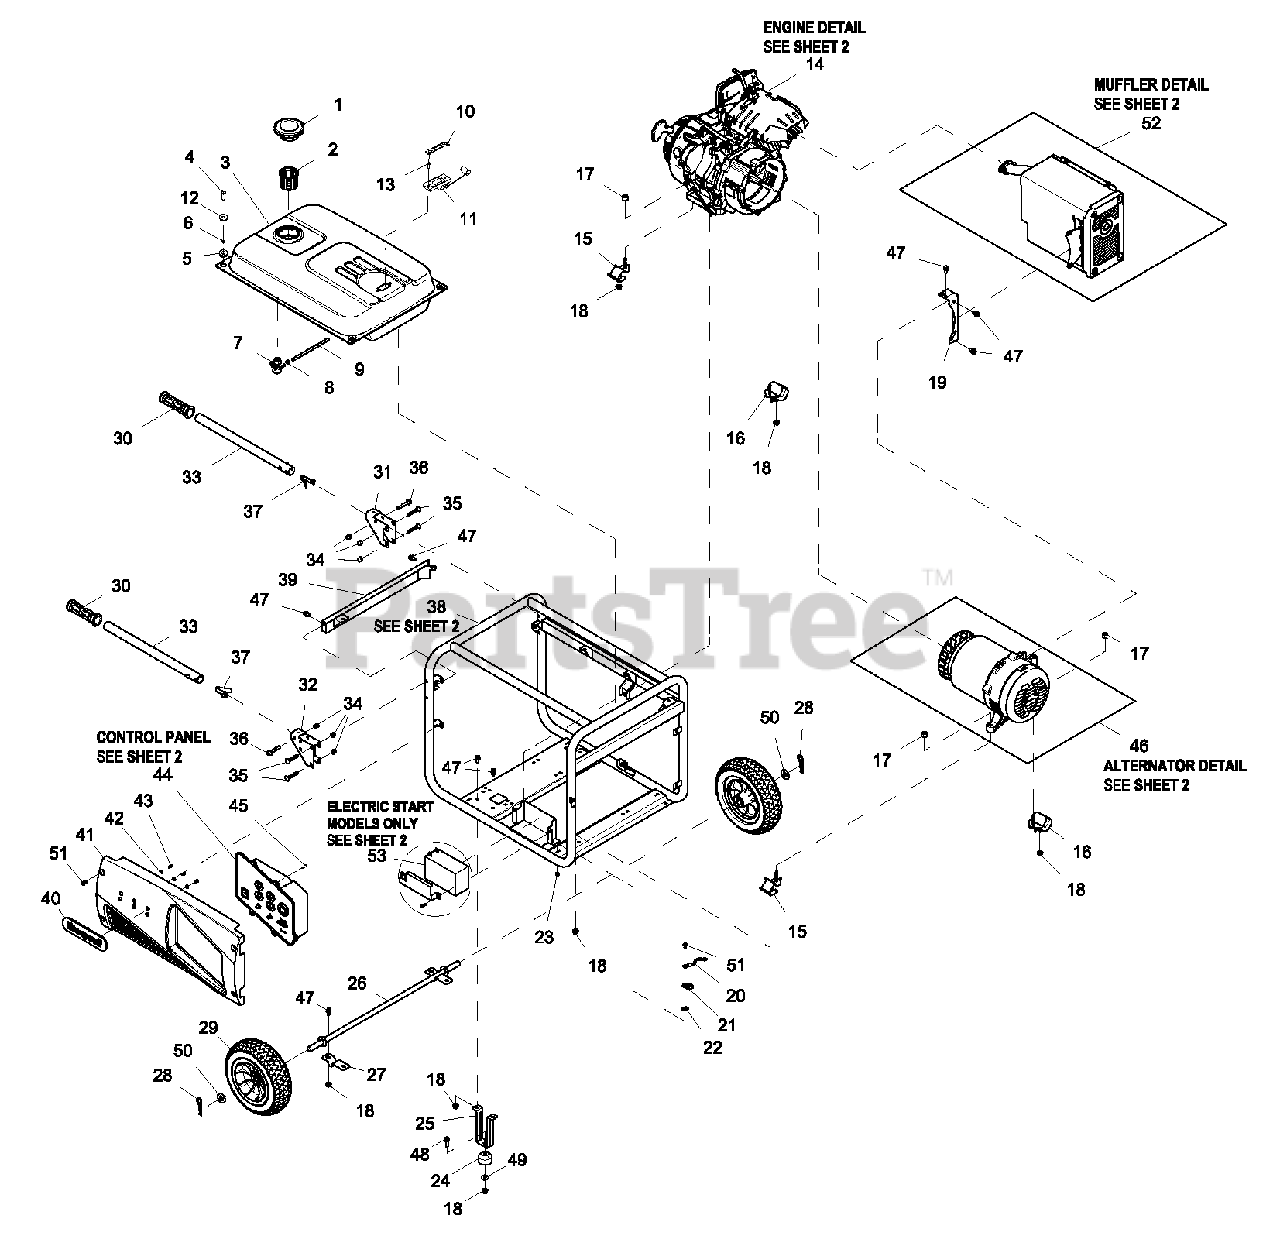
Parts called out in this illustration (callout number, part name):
1	FUEL CAP,VENTED,BLACK CAP
2	FILTER, FUEL
3	FUEL TANK 5.8GALHNYWL
4	SCREW HHFC M6-1.0X25FTH
5	RUBBER MOUNT,10.3 ID X11 HGT
6	INSERT, ANTI-CRUSH FOR TANKS
7	VALVE FUEL SHUTOFF
8	CLAMP HOSE BAND SPRING .38
9	FUEL HOSE 4 ID X 8.50D X165MM
10	PLATE, FUEL GAGE
11	FUEL GAGE, 90MM LONG ARM
12	WASHER FLAT .266ID X 1.00D
13	SCREW PFHMM5-0.8X 12
14	ENGINE HNYWL
15	VIB MNT45DEG M8X13.5/M10X37.5
16	VIB MNT45DEG M8X15.5/M10X37.5
17	NUT HEX FL WHIZ M10-1.25
18	NUT HEX FLWHIZM8-1.25
19	BRACKET, MUFFLER 389CC
20	GND WIRE PORT BRG CARR-FRAME
21	LUG GROUNDING HONEYWELL
22	WASHER LOCK SPECIAL 1/4"
23	NUT HEX M6-1.0 G8 CLEAR ZINC
24	RUBBER FOOT
25	BENT FOOT HONEYWELL
26	WELDMENT AXLE AND BRACKET HW
27	AXLE BRACKET HONEYWELL
28	COTTER HAIRPIN 2.56X.80
29	WHEEL 10.25" OD 5/8" AXLE
30	GRIP HANDLE HONEYWELL
31	BRACKET HANDLE LH HW PORT
32	BRACKET HANDLE RH HW PORT
33	HANDLE, HW PORTABLE
34	CAP NUT M8-1.25 BLACK ZINC
35	CHB M8-1.25 X 40MM LONG
36	SCREW,HHFC M8-1.25X45
37	SNAP BUTTON - .437" DIA. HEAD
38	CRADLE WELDMENT HNYWL
39	WELDMENT END RAIL HONEYWELL
40	BADGE, HW SIDE PANEL
41	PANEL, PLASTIC SIDE C-PNL PORT
42	WASHER FLAT #8 ZINC
43	SCREW PPPH #8-16 X 0.40" BZC
44	CONTROL PANEL HONEYWELL
45	SCREW PPPH #8-16 X .66" BZC
46	ASSY ALTERNATOR
47	SCREW HHFC M8-1.25 X14 W/M10
48	SCREW HHFC M8-1.25 X 25 W/M10
49	WSHR FLAT 22.60D X 8.6ID X3
50	WASHER FLAT 5/8 ZINC
51	SCREW HHFC M6-1.0X14
52	MUFFLER HNYWL
53	BATTERY 12V10AH SEALED
